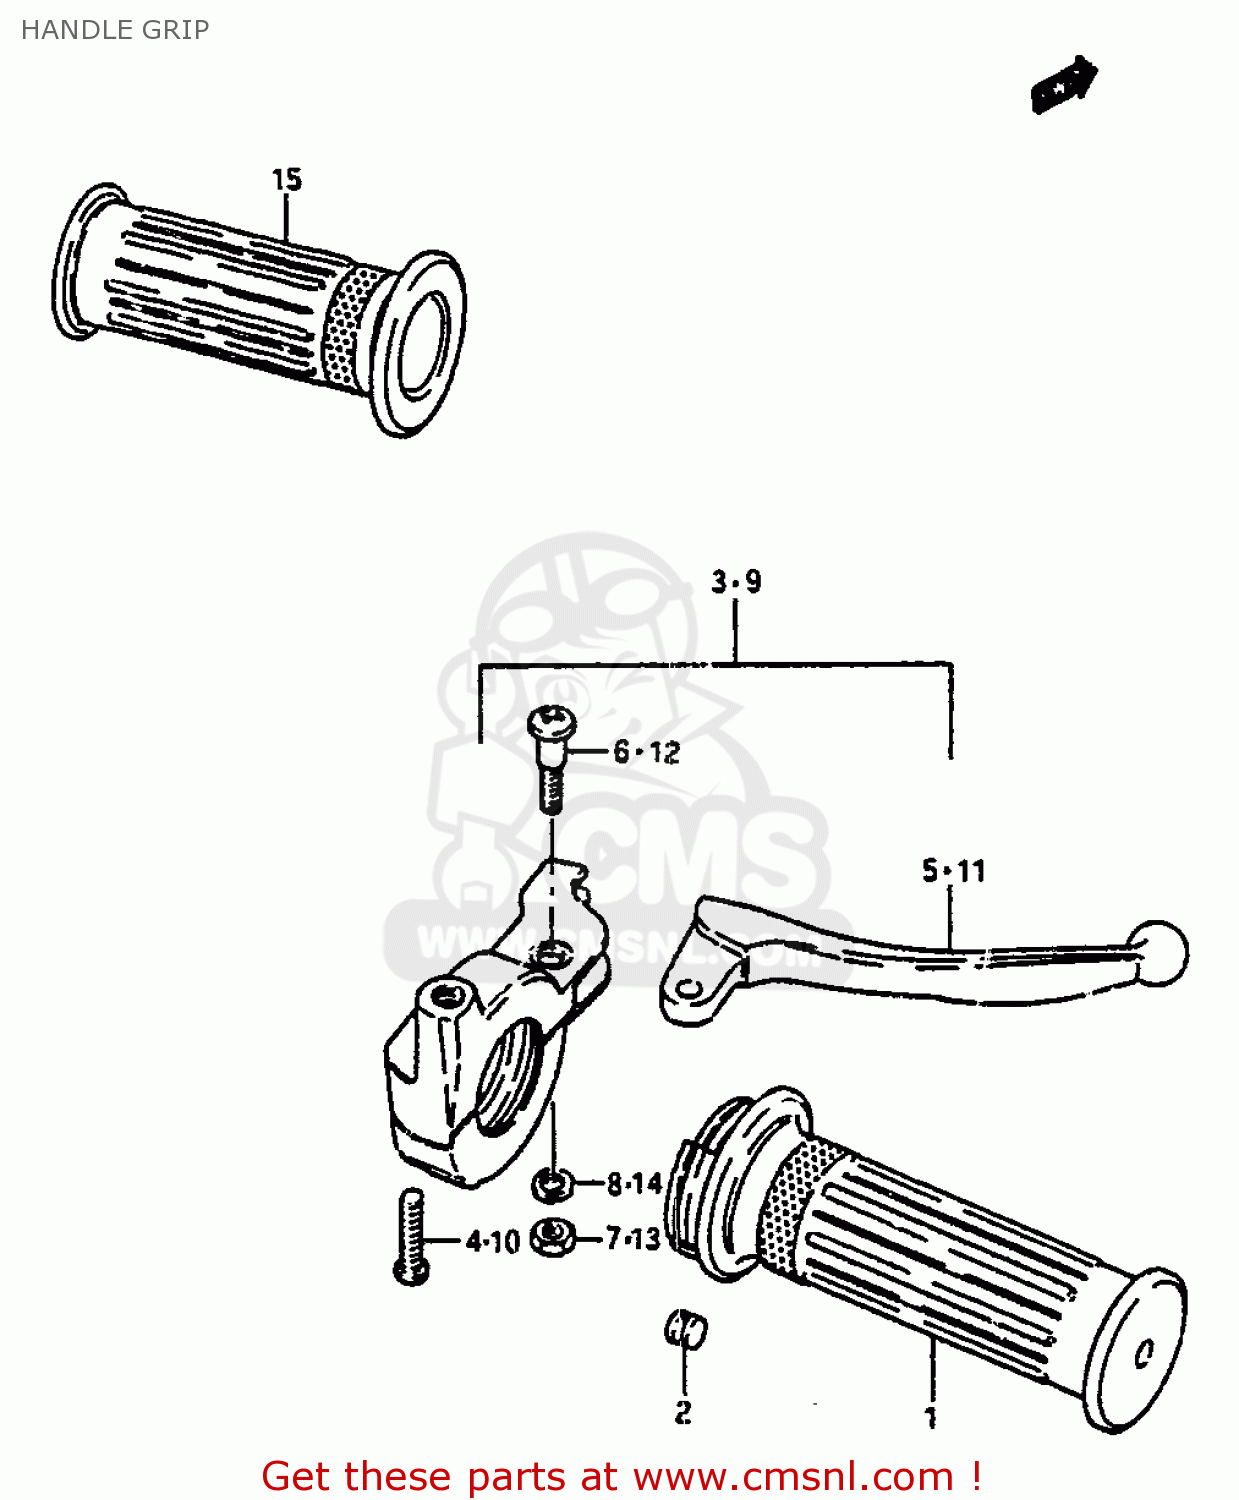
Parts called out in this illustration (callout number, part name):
1	GRIP,THROTTLE
2	PIECE,THROTTLE END
3	LEVER ASSY,BRAKE
4	SCREW
5	LEVER,BRAKE
6	SCREW
7	NUT
8	LOCK WASHER
9	LEVER ASSY,BRAKE
10	SCREW(5X22)
11	LEVER,BRAKE
12	SCREW,BRAKE LEVER PIVOT
13	NUT ,5MM
14	WASHER,LOCK
15	GRIP,L
